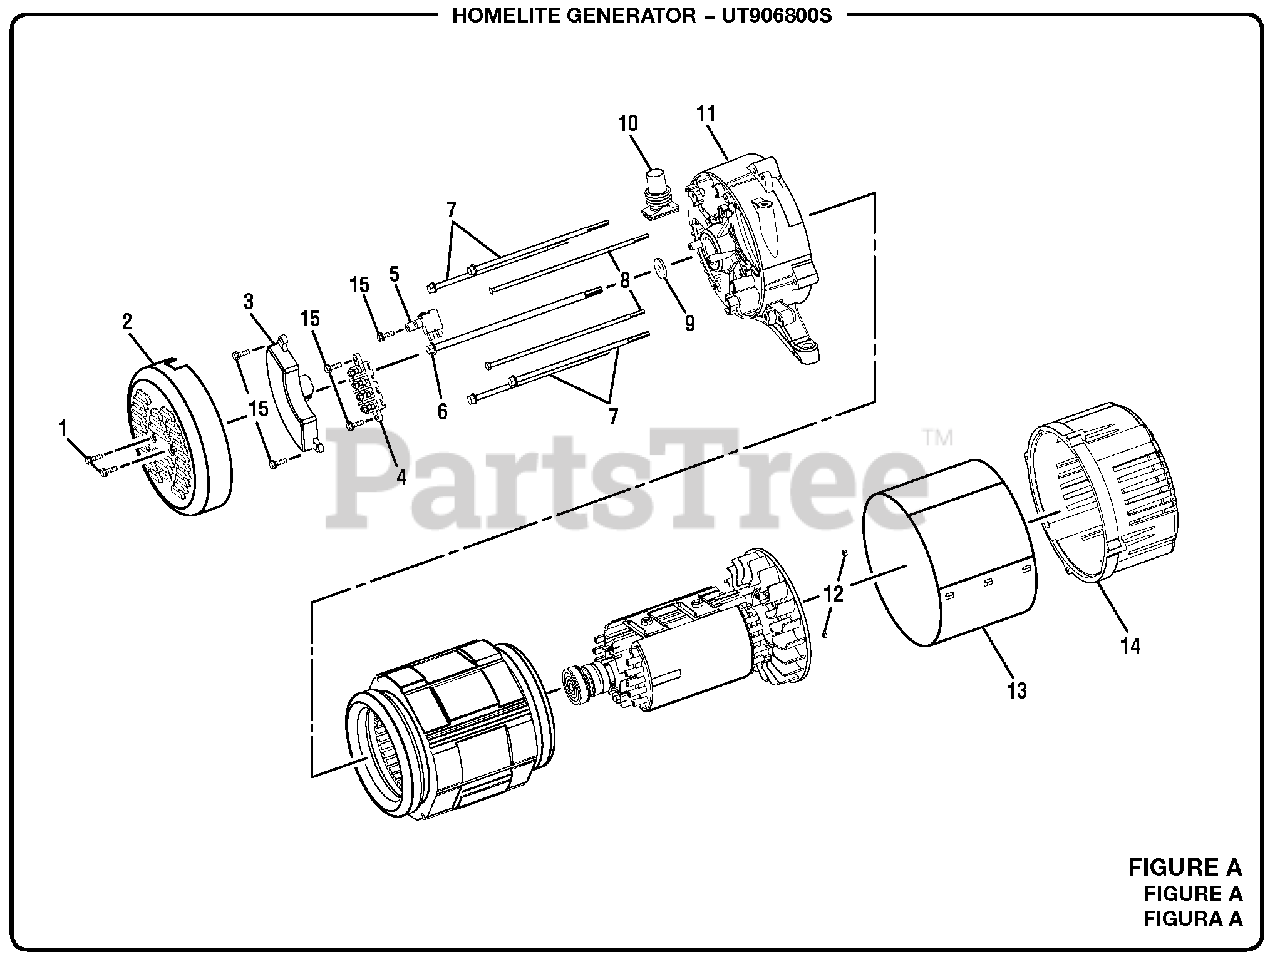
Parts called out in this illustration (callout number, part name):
1	Bolt (M5 x 12 mm, Hex Hd.)
2	Brush Cover
3	Automatic Voltage Regulator
4	Terminal Block
5	Brush Assembly
6	Bolt (5/16-24 x 235 mm, Hex Washer Hd.)
7	Bolt (M6 x 188 mm, Hex Washer Hd.)
8	Bolt (M5 x 210 mm, Hex Washer Hd.)
9	Washer (8 x 26 x 3t)
10	Rubber Boot
11	Bearing Housing
12	Hex Nut (M5)
13	Generator Head Cover
14	Adaptor Housing
15	Bolt (M5 x 16 mm, Hex Hd.)
